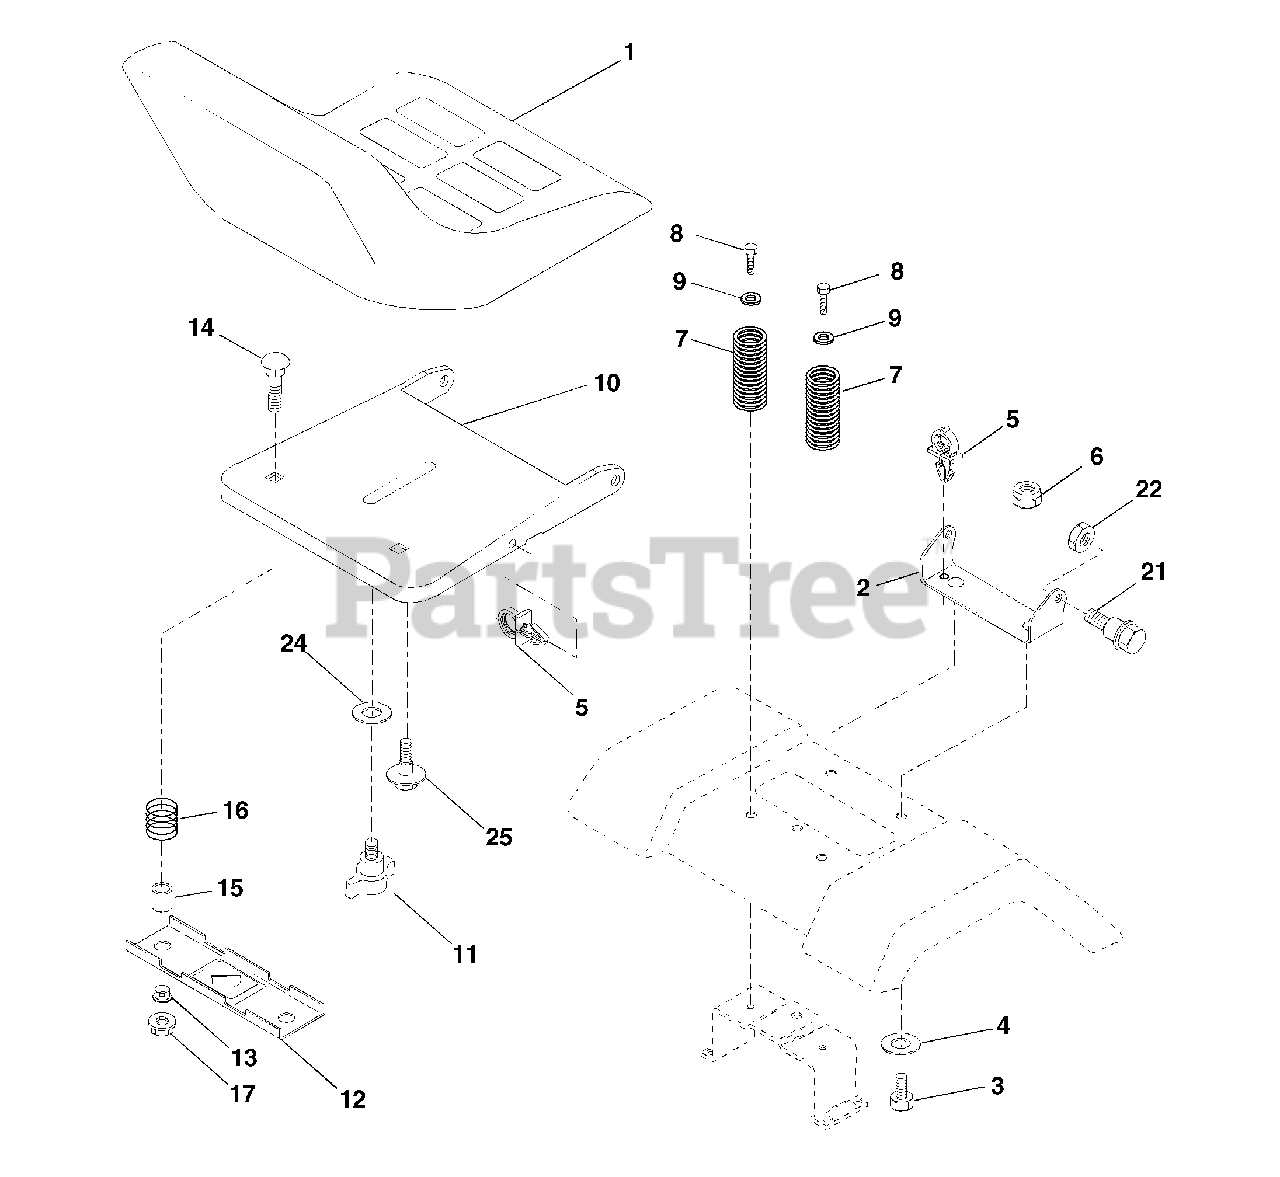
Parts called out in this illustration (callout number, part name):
1	Seat
2	Bracket Pivot Seat 8 720
3	Bolt Fin Hex 3/8-16 Unc X 1
4	Washer 13/32 X 1 X 10 Ga
5	Clip Push-In
6	Nut Hex w/Ins. 3/8-16 Unc
7	Spring Seat Cprsn 2 250 Blk Zi
8	Screw 3/8-16 X 1.5
9	Washer 13/32 X 1 X 14 Ga.
10	Pan Seat
11	Knob Seat
12	Bracket Mounting Switch
13	Bushing Snap Blk Nyl 50 Id
14	Bolt Rdhd Sqnk 1/4-20x1-1/2
15	Spacer Split 28x 88
16	Spring Cprsn
17	Nut Lock 1/4 Lge Flg Gr 5 Zinc
21	Bolt Shoulder 5/16-18 Unc
22	Nut Hex Lock W/Ins 5/16-18
24	Washer 17/32 X 1-3/16 X 12 Ga.
25	Bolt Shoulder 5/16-18 X 62
